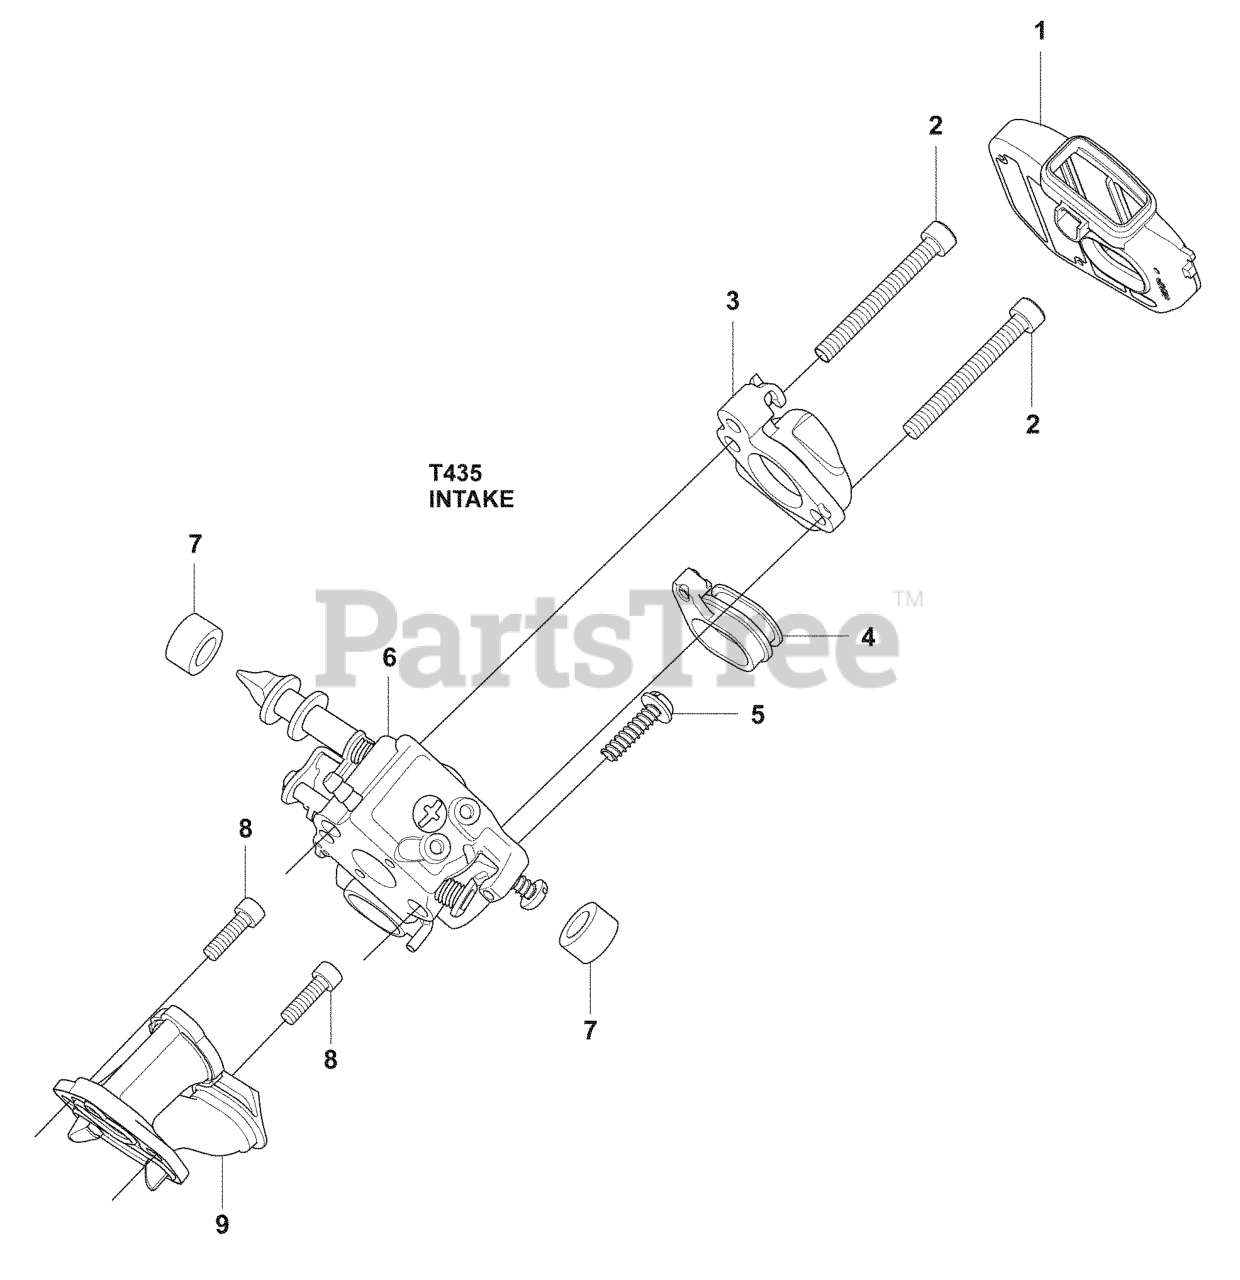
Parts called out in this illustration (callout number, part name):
1	RP AIR FILTER ASSY
2	BOLT
3	%MANIFOLD
4	RP SEAL
6	CARBURETOR WT 942
7	SEAL
9	PIPE, INLET
